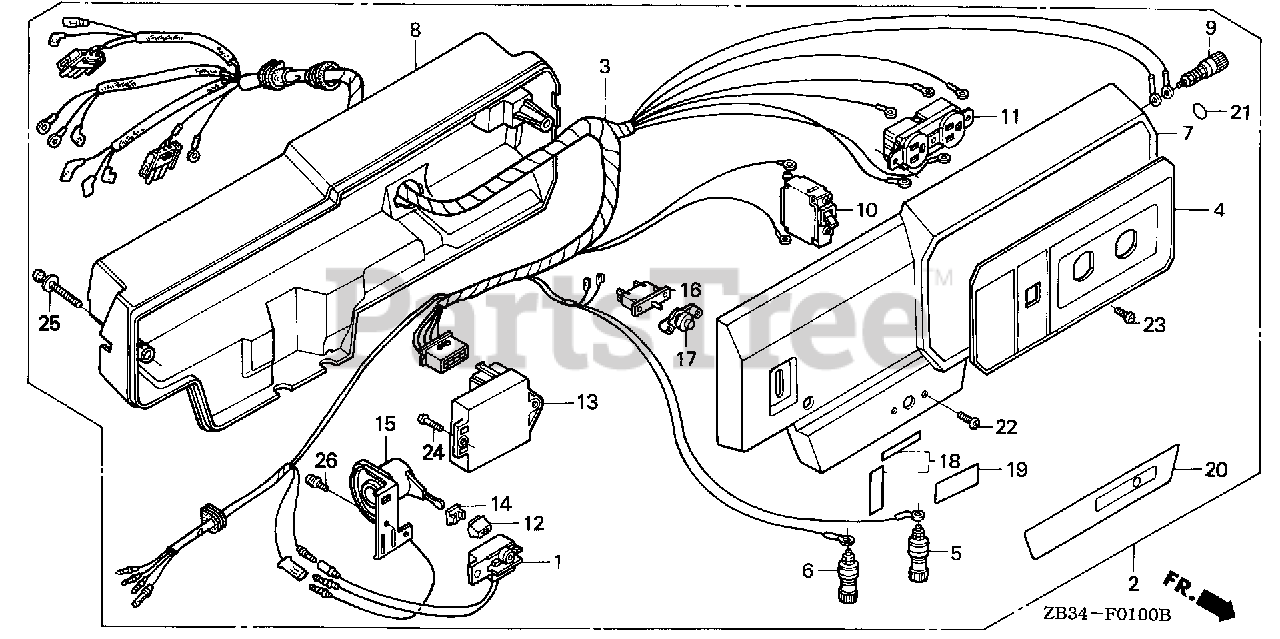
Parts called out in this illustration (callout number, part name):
1	ALERT UNIT, OIL (NOT AVAILABLE)
2	BOX ASSY., CONTROL *R8* (BRIGHT RED)
3	WIRE HARNESS ASSY.
4	MARK, SWITCH PANEL
5	TERMINAL, D.C. OUTPUT (+)
6	TERMINAL, D.C. OUTPUT (-)
7	PANEL, CONTROL *R8* (BRIGHT RED)
8	CASE, CONTROL *R8* (BRIGHT RED)
8	CASE, CONTROL *R280* (POWER RED)
9	TERMINAL ASSY., GROUND
10	BREAKER, CIRCUIT (13A)
11	RECEPTACLE (15A-125V)
12	KNOB, PETCOCK LEVER
13	REGULATOR UNIT, AUTOMATIC VOLTAGE
14	BUSH, CONTROL KNOB
15	SWITCH ASSY., ENGINE
16	PROTECTOR, CIRCUIT (D.C.)
17	LENS ASSY., PROTECTOR
18	MARK, SWITCH (NOT AVAILABLE)
19	MARK, OIL ALERT (NOT AVAILABLE)
20	MARK, D.C. OUTPUT (NOT AVAILABLE)
21	MARK, GROUND
22	SCREW, PAN (3X12)
23	SCREW, PAN (4X6)
24	SCREW, PAN (5X8)
25	SCREW-WASHER (6X45)
26	SCREW-WASHER (4X8)
